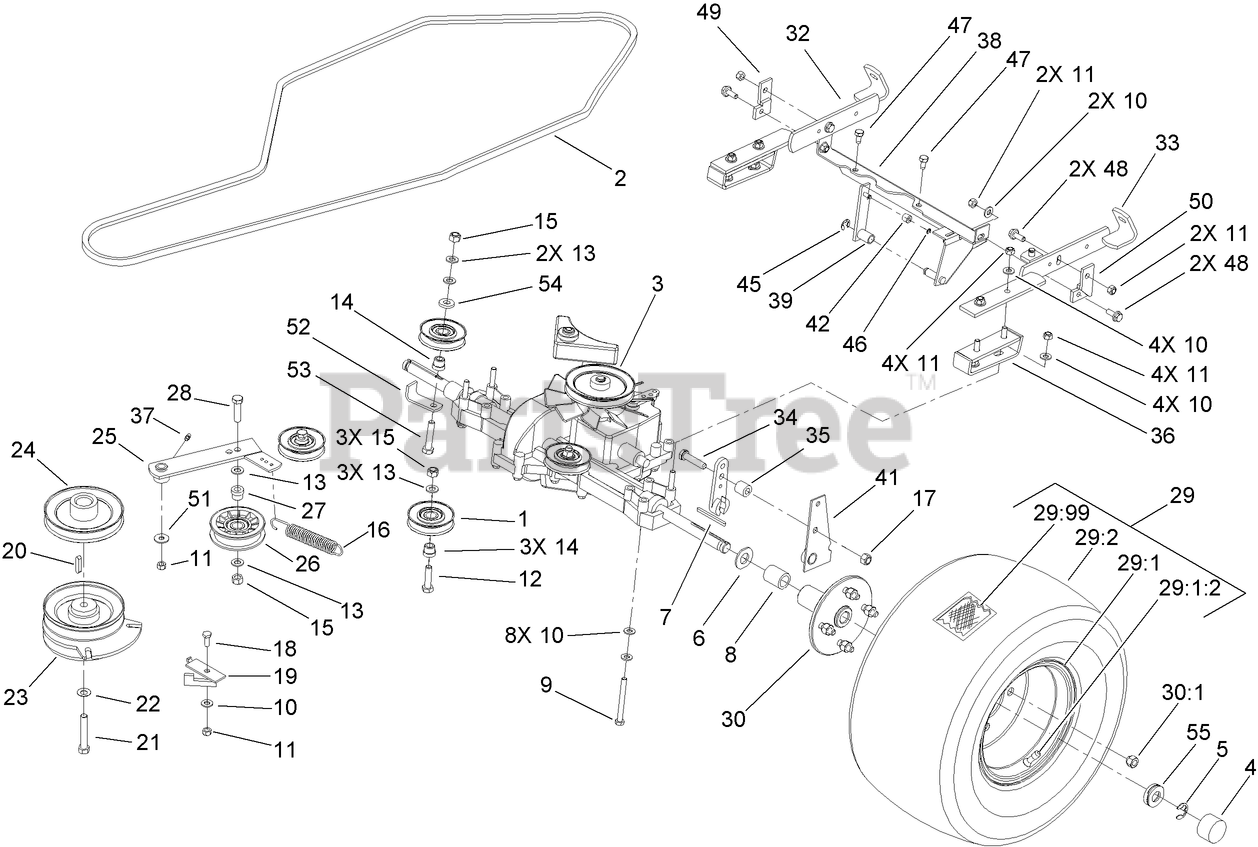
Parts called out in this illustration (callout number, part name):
1	PULLEY-IDLER
2	V-BELT-TRACTION
3	TRANSMISSION
4	CAP-HUB
5	CLIP-SPRING
6	WASHER
7	KEY-SQUARE
8	SPACER-AXLE
9	SCREW-HH
10	WASHER-PLAIN
11	NUT-LOCK, NI
12	SCREW-HH
13	WASHER-FLAT
14	BUSHING-IDLER
15	NUT-LOCK, NI
16	SPRING
17	NUT-LOCK, NI
18	SCREW-HH
19	RETAINER
20	KEY-SQUARE
21	SCREW-HH
22	WASHER-SPRING, BELLEVILLE
23	CLUTCH-ELECTRIC
24	PULLEY-ENGINE
25	ARM-IDLER
26	PULLEY-IDLER
27	BUSHING-IDLER
28	SCREW-HH
29	REAR WHEEL COMPLETE
29:1	RIM ASSEMBLY
29:2	TIRE
30	HUB-WHEEL
30:1	NUT-LUG
32	Bracket-Right
33	Bracket-Left
34	SCREW-HH
35	SLEEVE
36	BRACKET-SUPPORT
37	FITTING-GREASE
38	Bar ASM
42	Roller
45	Stirrup
46	STIRRUP
47	SCREW-THREAD FORMING
48	SCREW-HEX
49	BRACKET-RIGHT
50	BRACKET-LEFT
51	WASHER-PLAIN
52	RETAINER-BELT
53	SCREW-HH
54	WASHER-FLAT
55	RETAINER-CAP, HUB
